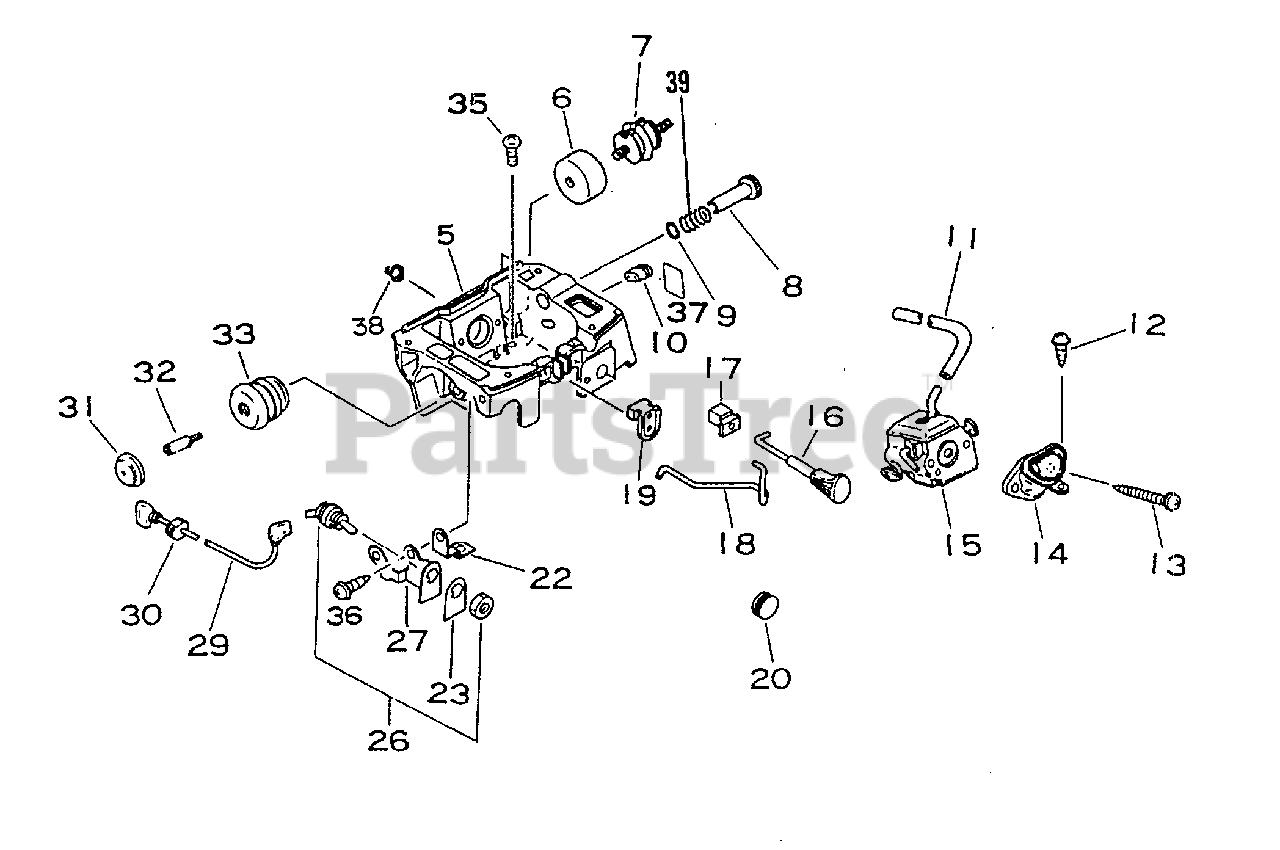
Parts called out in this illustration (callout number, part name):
5	CASE, CARBURETOR
6	PLATE, CUSHION
7	CUSHION
8	SCREW, IDLE ADJUST
9	O-RING - 6
11	PIPE - IMPULSE
12	SCREW - 5X14
13	SCREW - 5X55
14	GASKET
15	CARBURETOR
16	ROD, CHOKE
17	GROMMET
18	ROD, THROTTLE
19	GUIDE, THROTTLE ROD
22	TERMINAL - GROUND
23	LABEL - SWITCH
26	IGNITION SWITCH ASSY
27	BRACKET, SWITCH
29	LEAD - GROUND
31	CAP, CUSHION
33	CUSHION
35	SCREW - 5X20
36	SCREW - 5X10
37	LABEL - IDLE
39	SPRING, IDLE ADJUST
